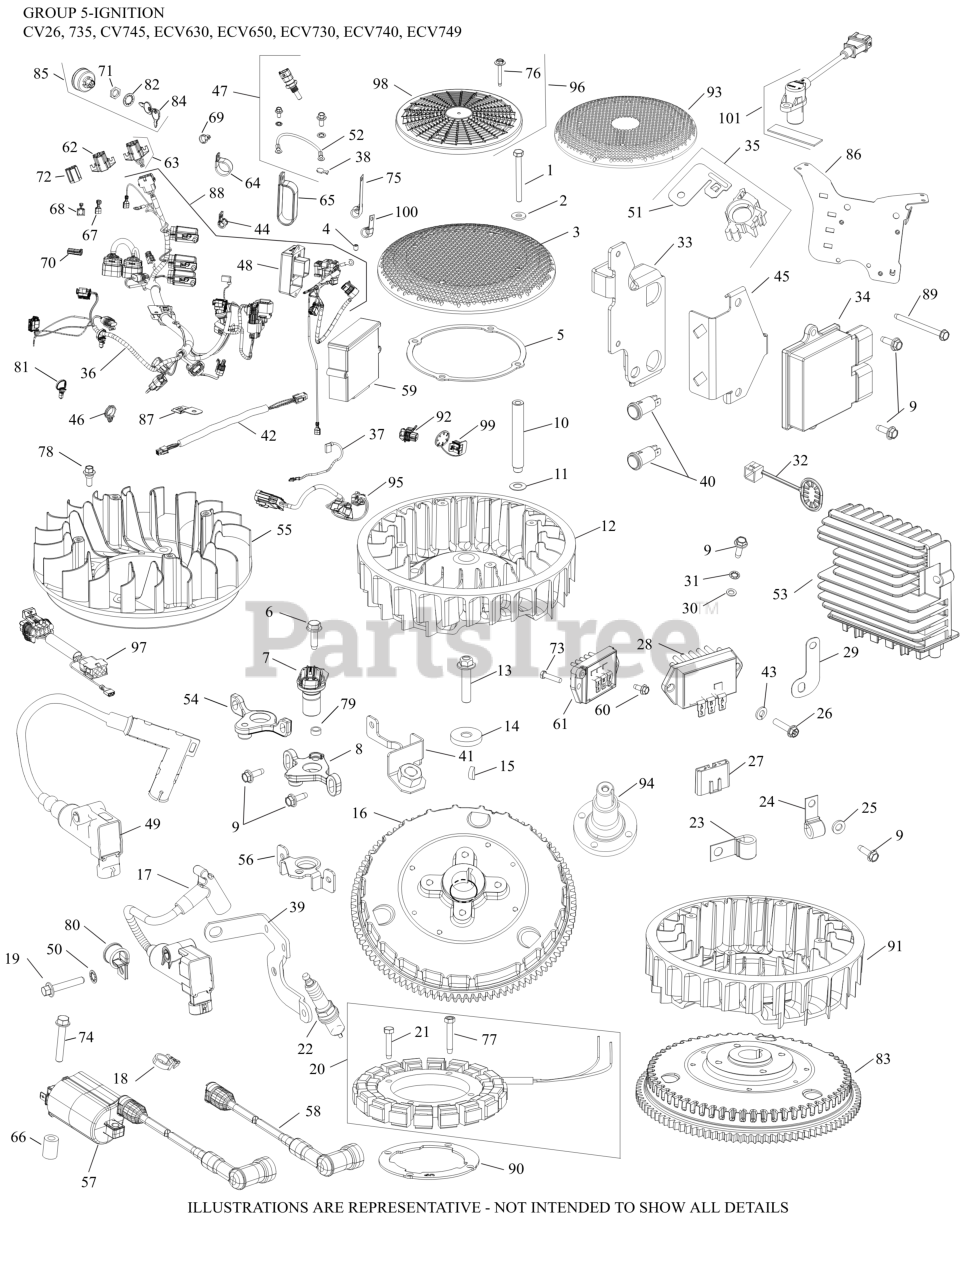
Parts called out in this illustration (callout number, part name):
1	SCREW, CAP M6X1.0X99.5
2	WASHER, FLAT 1/4" (O.D. 5/8")
3	SCREEN, GRASS
4	SCREW, SKT SET #10-24X1/4"
5	RING, SUPPORT
6	SCREW, THREAD FORMING
7	SENSOR, SPEED
8	BRACKET, SENSOR SPEED
9	SCREW, THREAD FORMING
11	WASHER, SPRING 10 MM
13	SCREW, FLG M10X1.5X45-USE 25 086 361-S
14	WASHER, FLAT 13/32"
15	KEY, 3/16" X 5/8"
16	FLYWHEEL ASSEMBLY
17	COIL, IGNITION - EFI
18	CLIP, SNAP-IN-USE 25 018 05-S
19	SCREW, THD FRM-USE 25 086 473-S
19	SCREW, FLG (BLACK) M6X1.0X34
20	KIT, 15 / 20 AMP STATOR
21	SCREW, THREAD FORMING
22	PLUG, SPARK (STD)
25	WASHER, FLAT 1/4" (O.D. 1/2")
26	SCREW, HEX FLANGE HI-LO
27	CONNECTOR
31	WASHER, INT TOOTH LOCK #10
32	CAP, CONNECTOR
33	BRACKET, ECU
34	MODULE, ECU ECV749
35	KIT, MOUNTING CLIP
36	KIT, HARNESS
46	RETAINER, WIRE HARNESS
50	WASHER, INT TOOTH LOCK 1/4"
51	CLIP USE 25 154 21-S
60	SCREW, THREAD FORMING
61	REGULATOR, RECTIFIER
65	CLAMP, INSULATED DOUBLE
